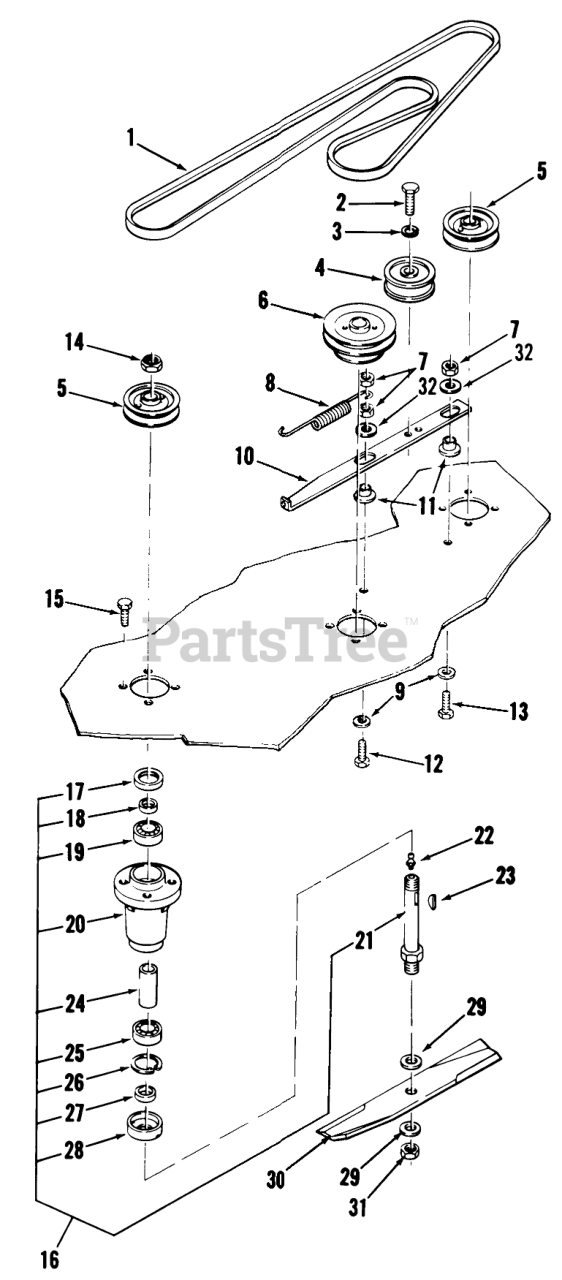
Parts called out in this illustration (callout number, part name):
1	V BELT
1	V-BELT
2	BOLT HEX SPECIAL
3	LOCKWASHER
4	Idler Pulley
5	PULLEY-BLADE DRIVE
6	PULLEY-42 MOWER SPDL
6	PULLEY-48 MOWER SPDL
7	NUT
8	SPRING-EXTENSION
9	WASHER
10	BAR-IDLER SUPPORT
11	SPACER-BUSHING
12	Bolt
13	Bolt
14	Nut
15	Bolt
16	Spindle Assembly
18	SPACER-SEAL
19	BEARING-BALL
20	HOUSING-SPINDLE
21	Spindle Shaft
22	Grease Fitting
23	Hi-Pro Key 3/16 x 5/8
24	SPACER
25	BEARING-BALL
26	Ring-Snap
27	SPACER-BLADE
28	CUP-SPINDLE
29	SpeciaI Washer
30	14IN BLADE KIT
30	BLADE KIT (3 PACK)
31	Nut
32	WASHER
